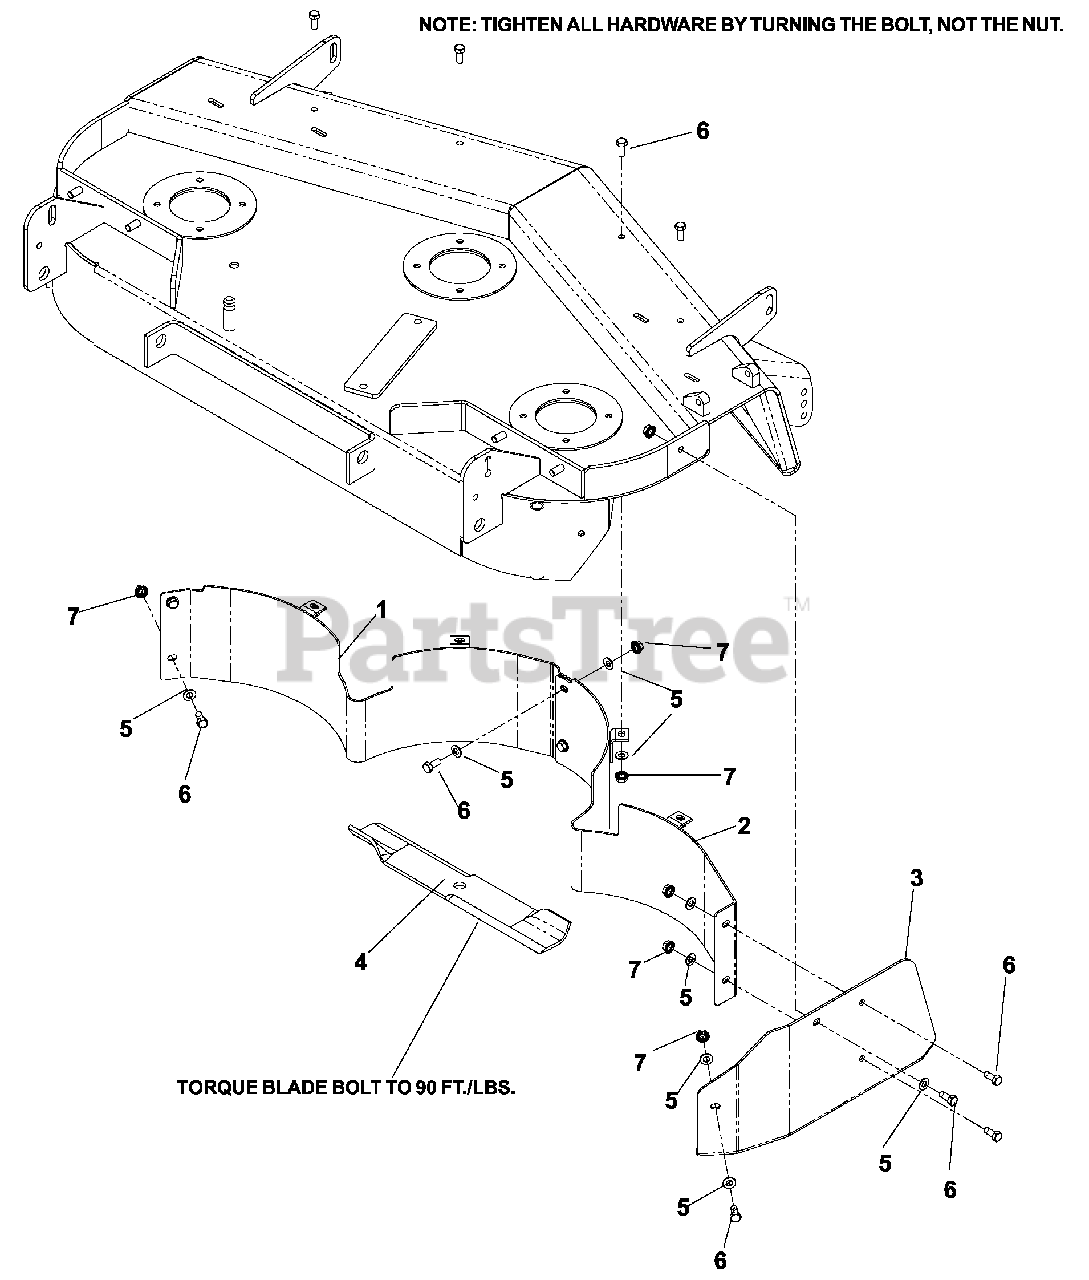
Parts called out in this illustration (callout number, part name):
1	48" BAFFLE, LEFT
2	48" BAFFLE, RIGHT
3	48" MULCH CAP
4	BLADE, MULCH, 16 1/4"
5	WASHER, 5/16, SAE
6	HCS, 5/16-18 X 3/4, GR5
7	NUT, 5/16C
